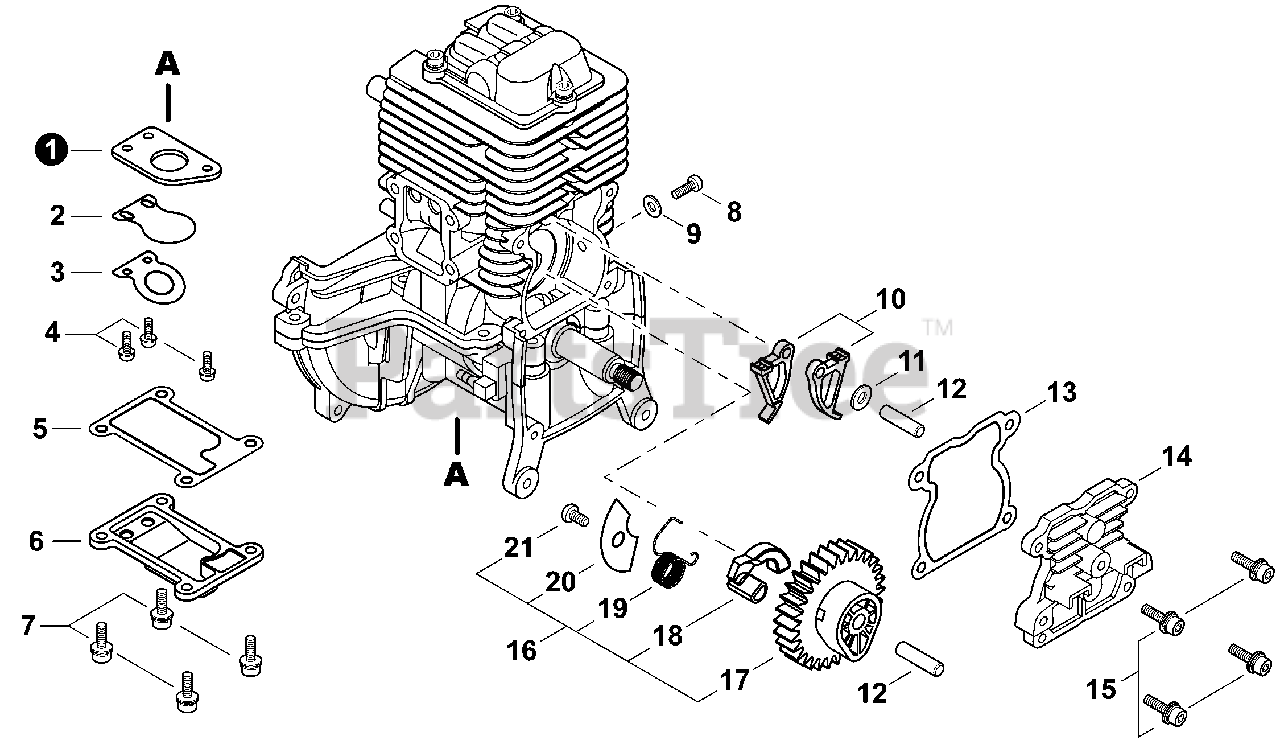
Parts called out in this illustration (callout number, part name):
1	PLATE, REED BACKING
2	VALVE, REED
3	STOP, REED VALVE
4	SCREW M3×10
5	GASKET, REED VALVE
6	COVER, REED VALVE
7	BOLT M4×14
8	SCREW M5
9	WASHER Ø10ר5.5×2
10	FOLLOWER, CAM
11	WASHER 5 MM
12	PIN, LOCATING Ø5×29.8 MM
13	GASKET, CAM GEAR
14	COVER, CAM GEAR
15	BOLT M4×14
16	CAM GEAR ASSY
17	GEAR, CAM
19	SPRING, COIL
20	PLATE, COVER
21	SCREW, TAPPING 4×6
